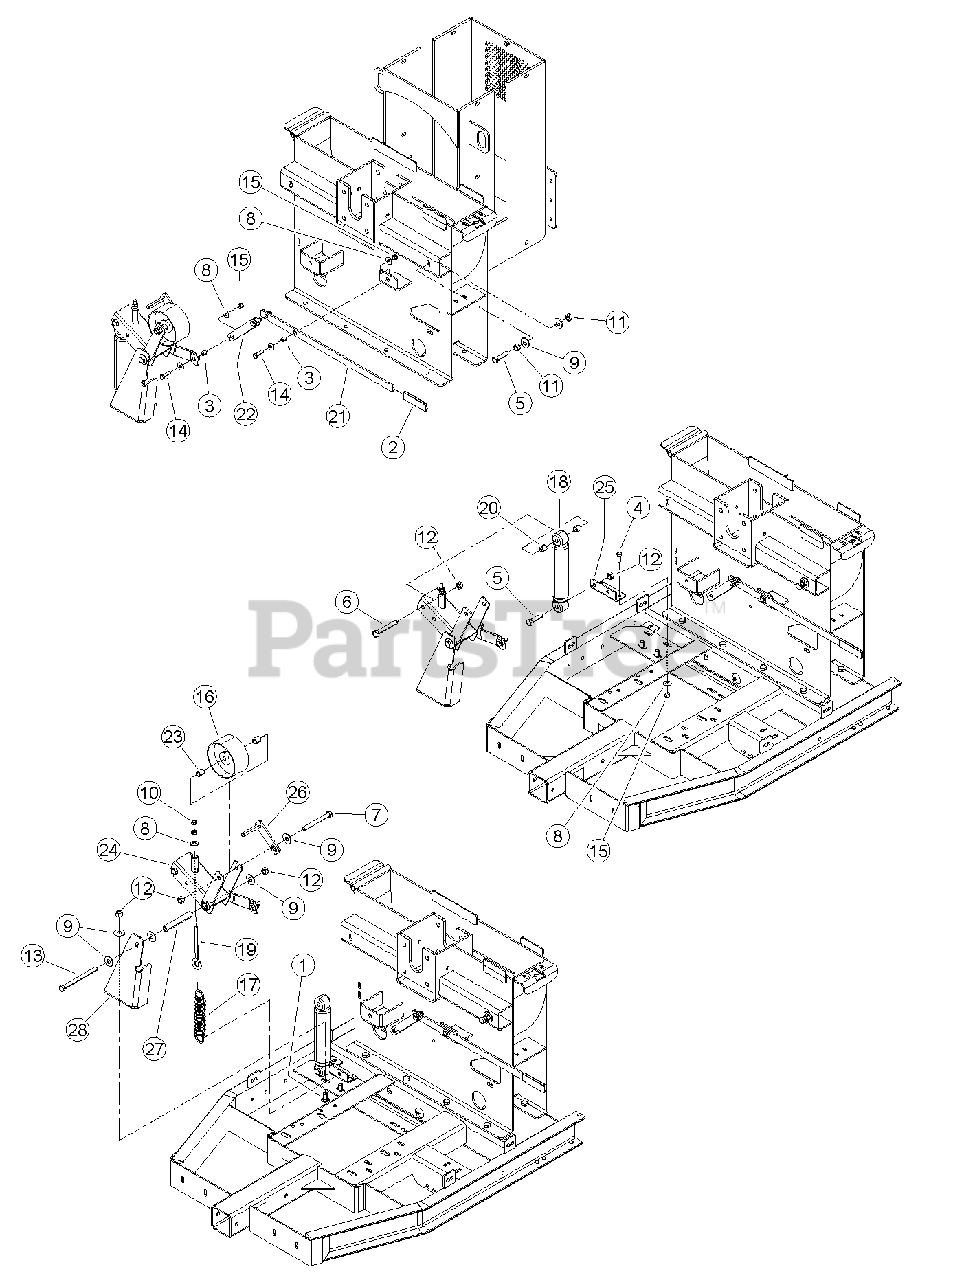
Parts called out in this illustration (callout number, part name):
1	BOLT, 1/2 X 1 CRG GR5 ZP
2	GRIP, CLUTCH HANDLE
3	BUSHING, 3/8 X 1/2 SLEEVE LUBE
4	BOLT, 3/8 X 1 HEX HD GR5 ZP
5	BOLT, 1/2 X 2 HEX HD GR5 ZP
6	BOLT, 1/2 X 3-1/2 HEX HD GR5 ZP
7	BOLT, 1/2 X 4-1/2 HEX HD GR5 NC ZP
8	WASHER, 3/8 FLAT ZP
9	WASHER, 1/2 FLAT ZP
10	NUT, 3/8 HEX NC ZP
11	NUT, 1/2 HEX NC ZP
12	NUT, 1/2 CENTERLOCK GRB ZP
13	BOLT, 1/2 X 6 HEX HD GR5 ZP
14	BOLT, 3/8 X 1-1/4 HEX HD GR5 ZP
15	NUT, 3/8 NE NYLOCK ZP
16	PULLEY, IDLER 5" X 2.50"
17	SPRING, 7-3/4" EXTENSION
18	ABSORBER, IDLER SHOCK
19	EYEBOLT, 3/8" X 5" LG 4-1/4 THD ZP
20	SPACER, 0.75 X 0.620
21	LEVER, CLUTCH ENGAGEMENT
22	LINK, ENGAGEMENT ARM
23	SPACER, IDLER SHEAVE
24	WELDMENT, IDLER ARM
25	BRACKET, SPRING ANCHOR
26	WELDMENT, BELT PIN
27	BUSHING, IDLER PIVOT
28	BRACE, IDLER
